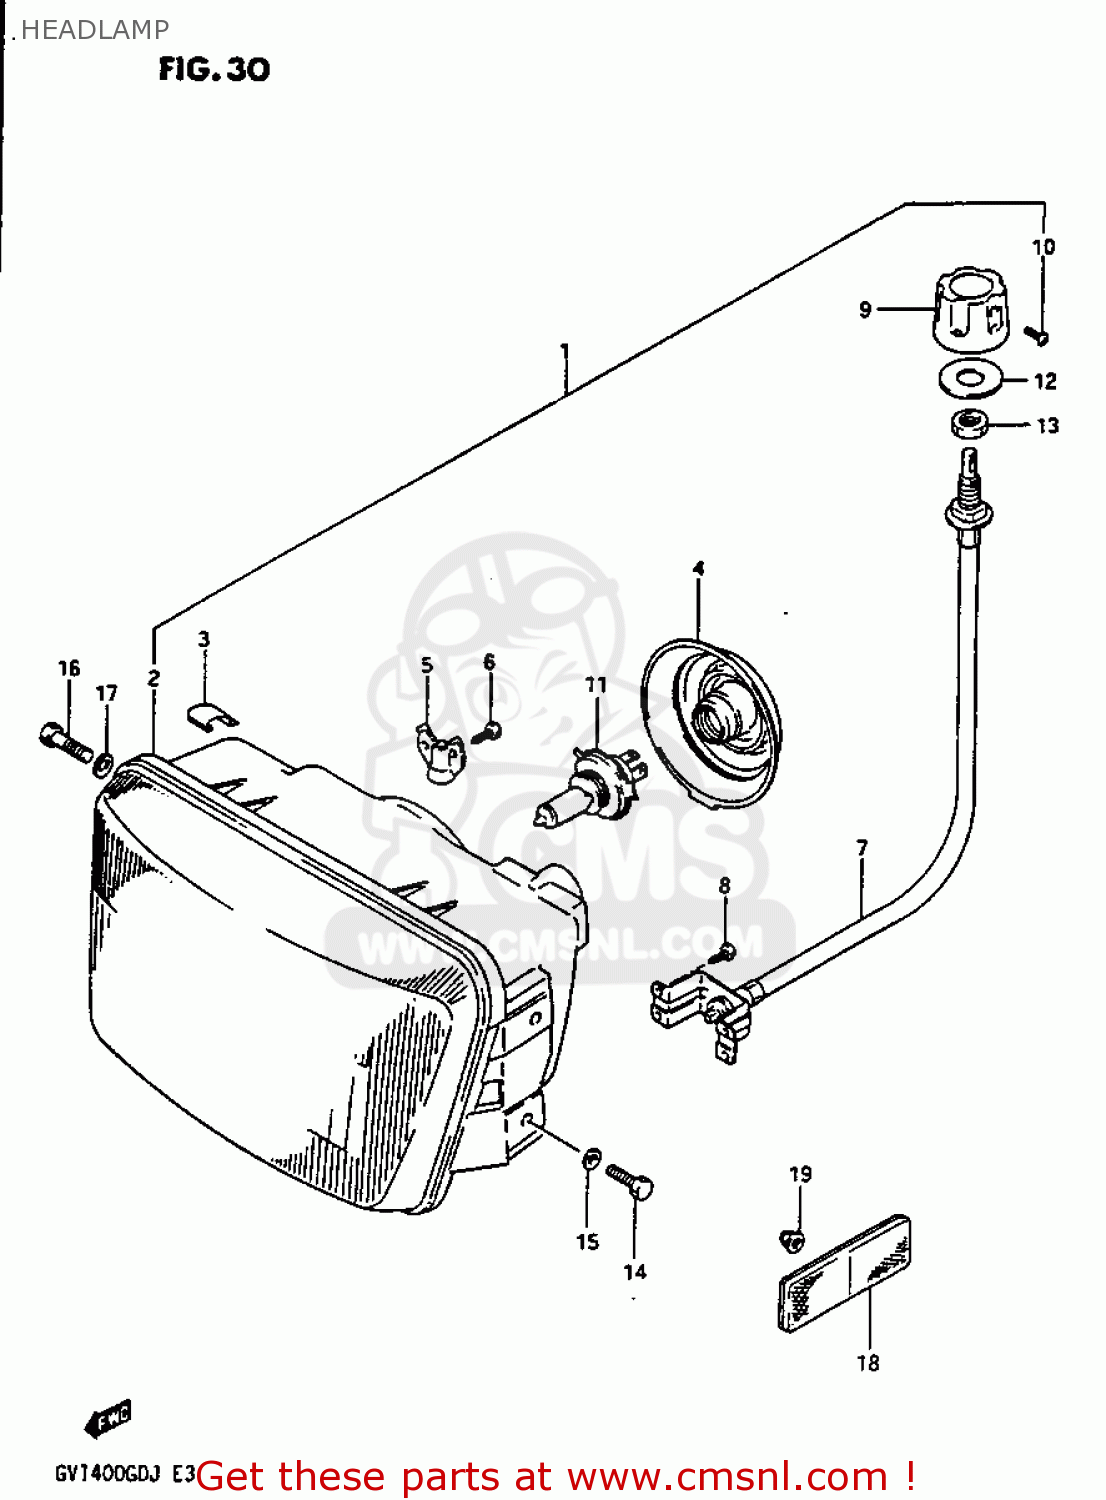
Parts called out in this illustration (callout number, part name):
1	HEADLAMP ASSEMBLY
2	LAMP UNIT
3	PLATE,HOOK
4	COVER,SOCKET
5	HOLDER
6	SCREW
7	CABLE,ADJUSTING
8	SCREW
9	KNOB,ADJUSTING
10	SCREW 3X12
11	BULB(12V60/55W,H4)
12	WASHER(12.5X32X2.3)
13	NUT
14	BOLT
15	WASHER,LOCK
16	BOLT ,6X35
17	WASHER
18	REFLEX REFLECTOR ASSY,FR SIDE
19	NUT 5MM
